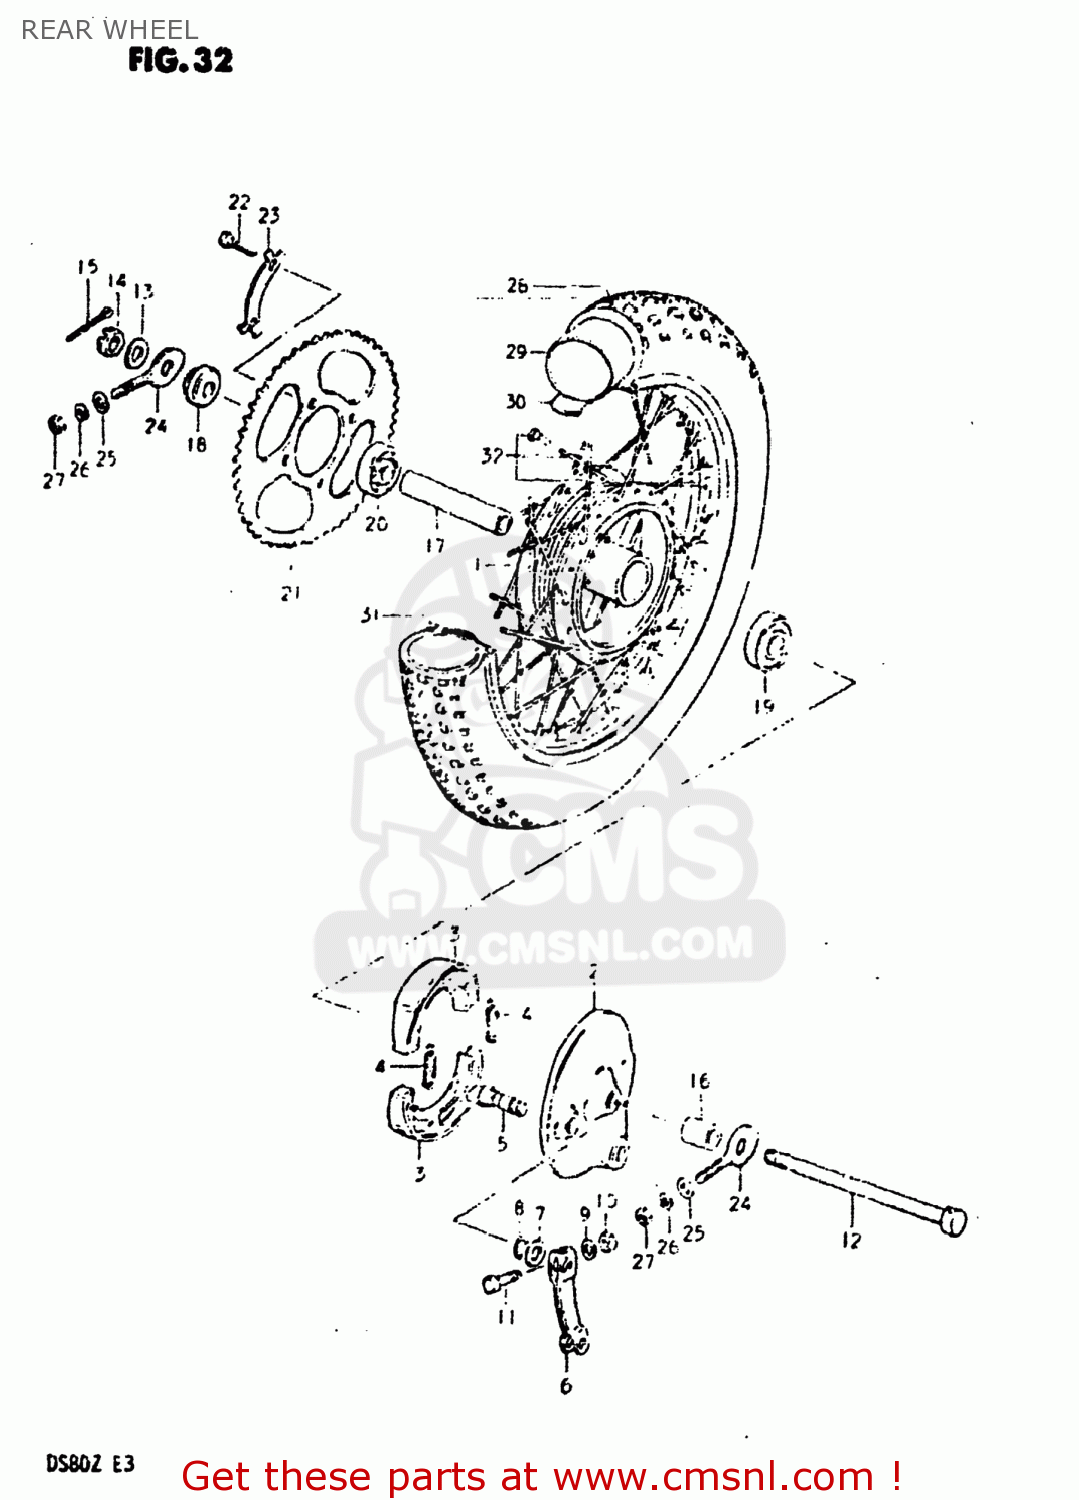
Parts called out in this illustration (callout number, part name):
1	HUB,RR
2	PANEL,REAR BRAKE ANCHOR
3	SHOE,BRAKE (MCA)
4	SPRING(L:34)
5	CAM,FRONT BRAKE
6	LEVER,REAR BRAKE CAM
7	WASHER (14.5X22X1.6)
8	O-RING (D:2.4 ID:13.8)
9	WASHER
10	NUT
11	BOLT(6X33)
12	AXLE,REAR
13	WASHER
14	NUT 12MM
15	COTTER PIN
16	SPACER (12.1X22X27)
17	SPACER(12.6X19X91)
18	SPACER,RR AXLE,L
19	BEARING
20	BEARING
21	SPROCKET,REAR
22	BOLT(8X25)
23	WASHER
24	ADJUSTER,CHAIN,R
25	WASHER
26	LOCK WASHER
27	NUT
28	TIRE
29	TUBE,INNER
30	PROTECTOR,INNER TUBE
31	RIM,RR WHEEL(1.60X12)
32	SPOKE SET,REAR WHEEL
